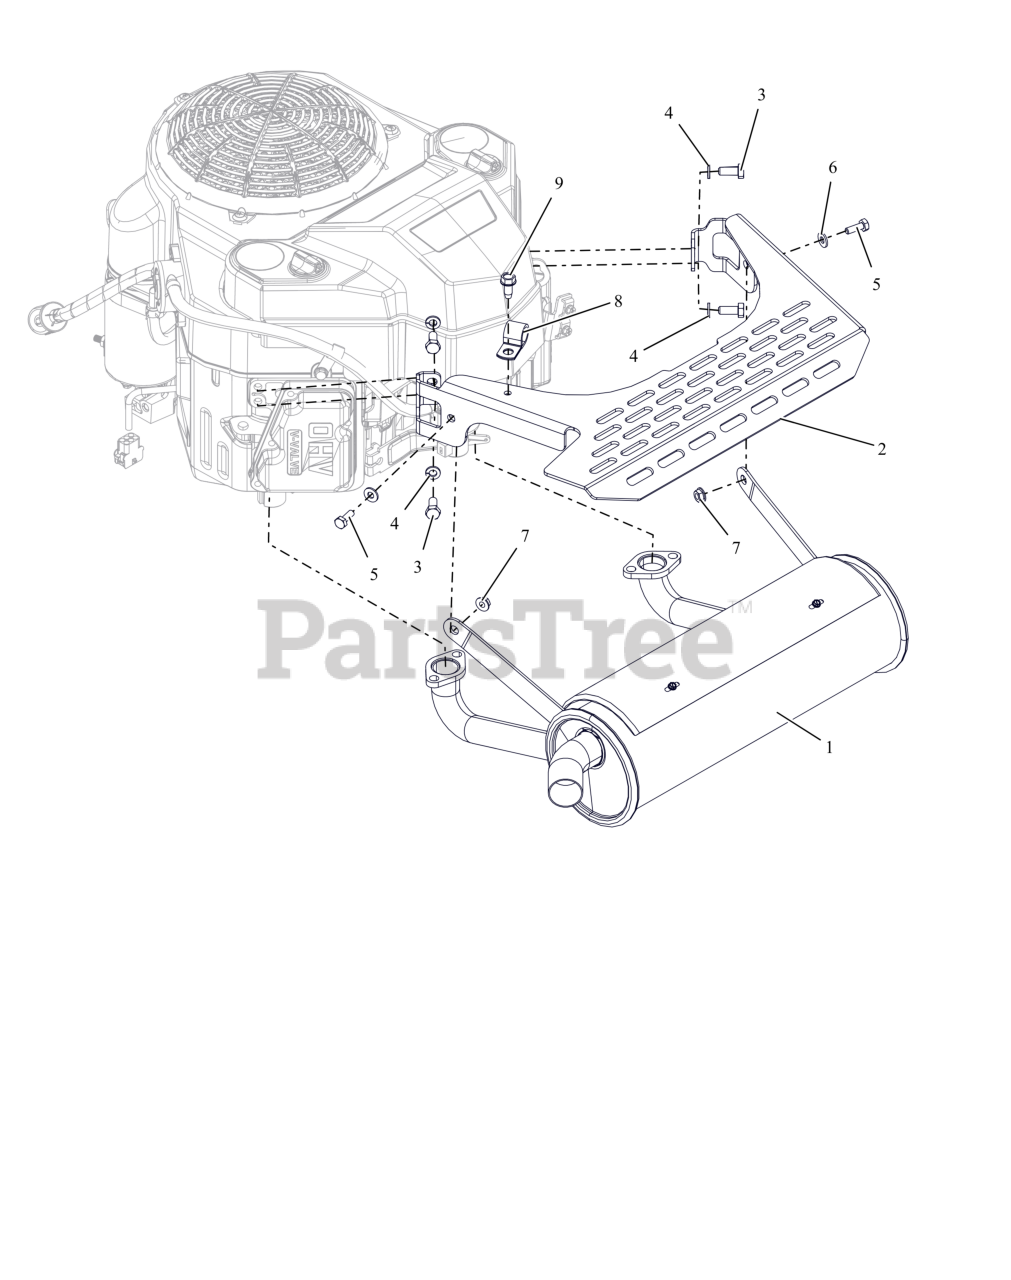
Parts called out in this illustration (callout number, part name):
1	EXHAUST, KAWASAKI PROSTANCE
2	SHIELD, MUFFLER
3	BLT, HEX M8-1.25X20 G8.8 ZCC
4	WSHR,LK-REG .312X.078 ZCC
5	BLT, HEX .25-20X.75 G5 ZCC
6	WSHR,FLT .281X.625X.065 ZCC
7	NUT-LK-CTR-FLG .25-20 ZC120
8	CLAMP, CUSHIONED STEEL .75
9	SCR,TAP .312-18X.75 HWH TR ZCC
